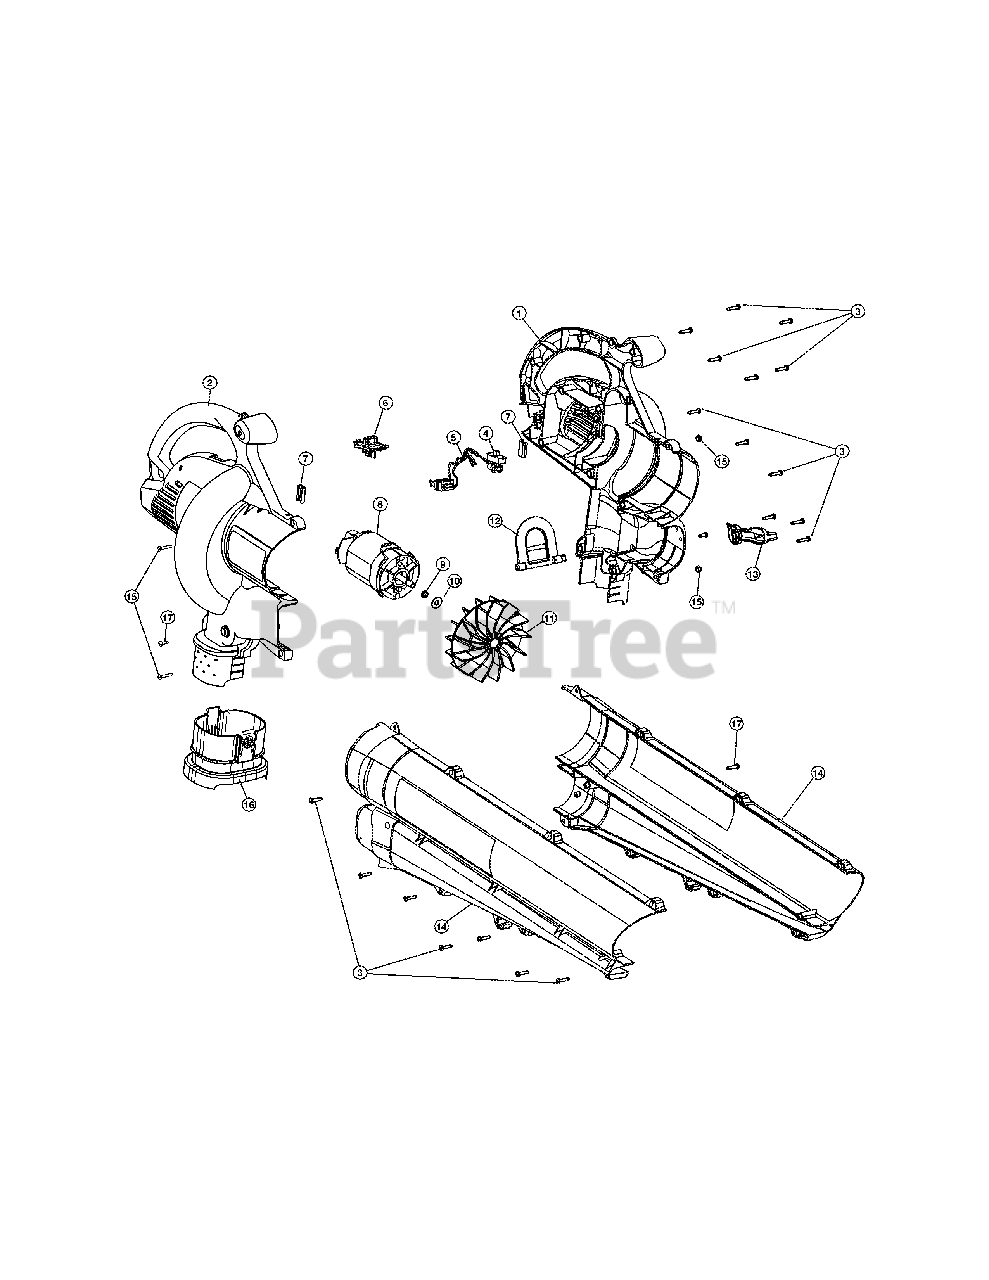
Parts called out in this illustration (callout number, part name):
1	Left Motor Housing
2	Right Motor Housing
3	Housing Screw
4	Switch Assembly
5	Power Connection Wire Assembly
6	Switch Lever
7	Rubber Cushion
8	Motor Assembly
11	Impeller
12	Mode Control Flapper
13	Mode Control Lever (Incl. Ref No. 3)
14	Blower/ Vac Tube Assembly (Incl. Ref No. 3)
15	Blower/ Vac Tube Mounting Hardware
16	Vacuum Bag Assembly
